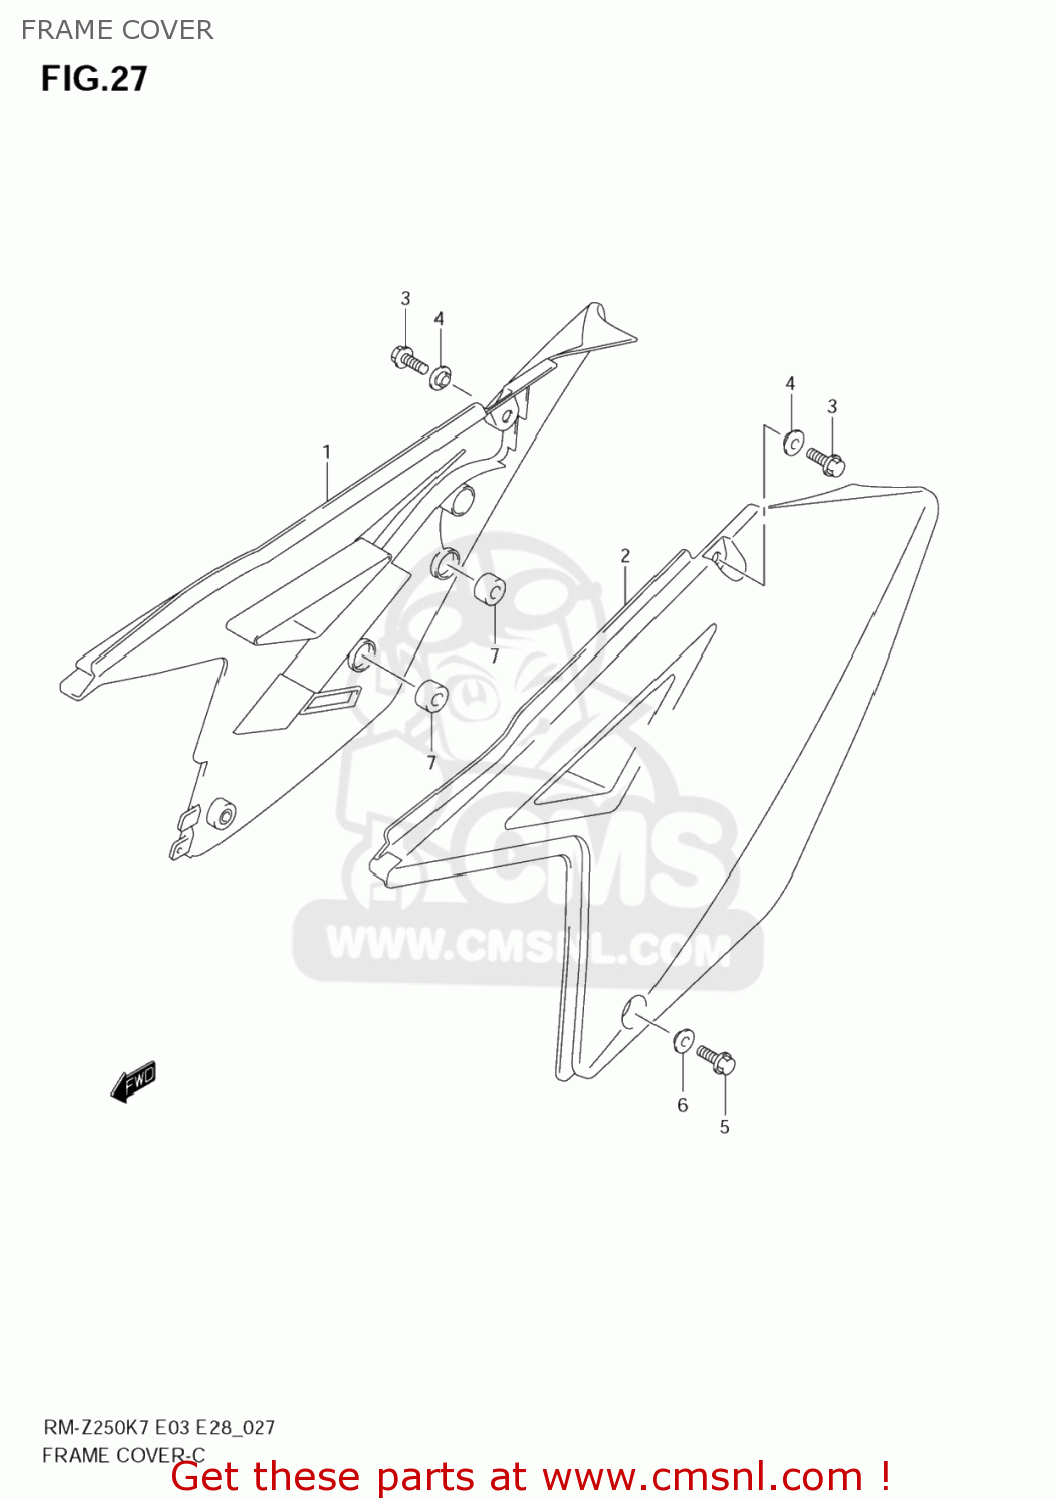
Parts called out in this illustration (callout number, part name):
1	COVER,FRAME R(WHITE)
2	COVER,FRAME,L(WHITE)
3	BOLT(6X16)
4	WASHER
5	BOLT(6X16)
6	WASHER
7	CUSHION,FRAME COVER,R
